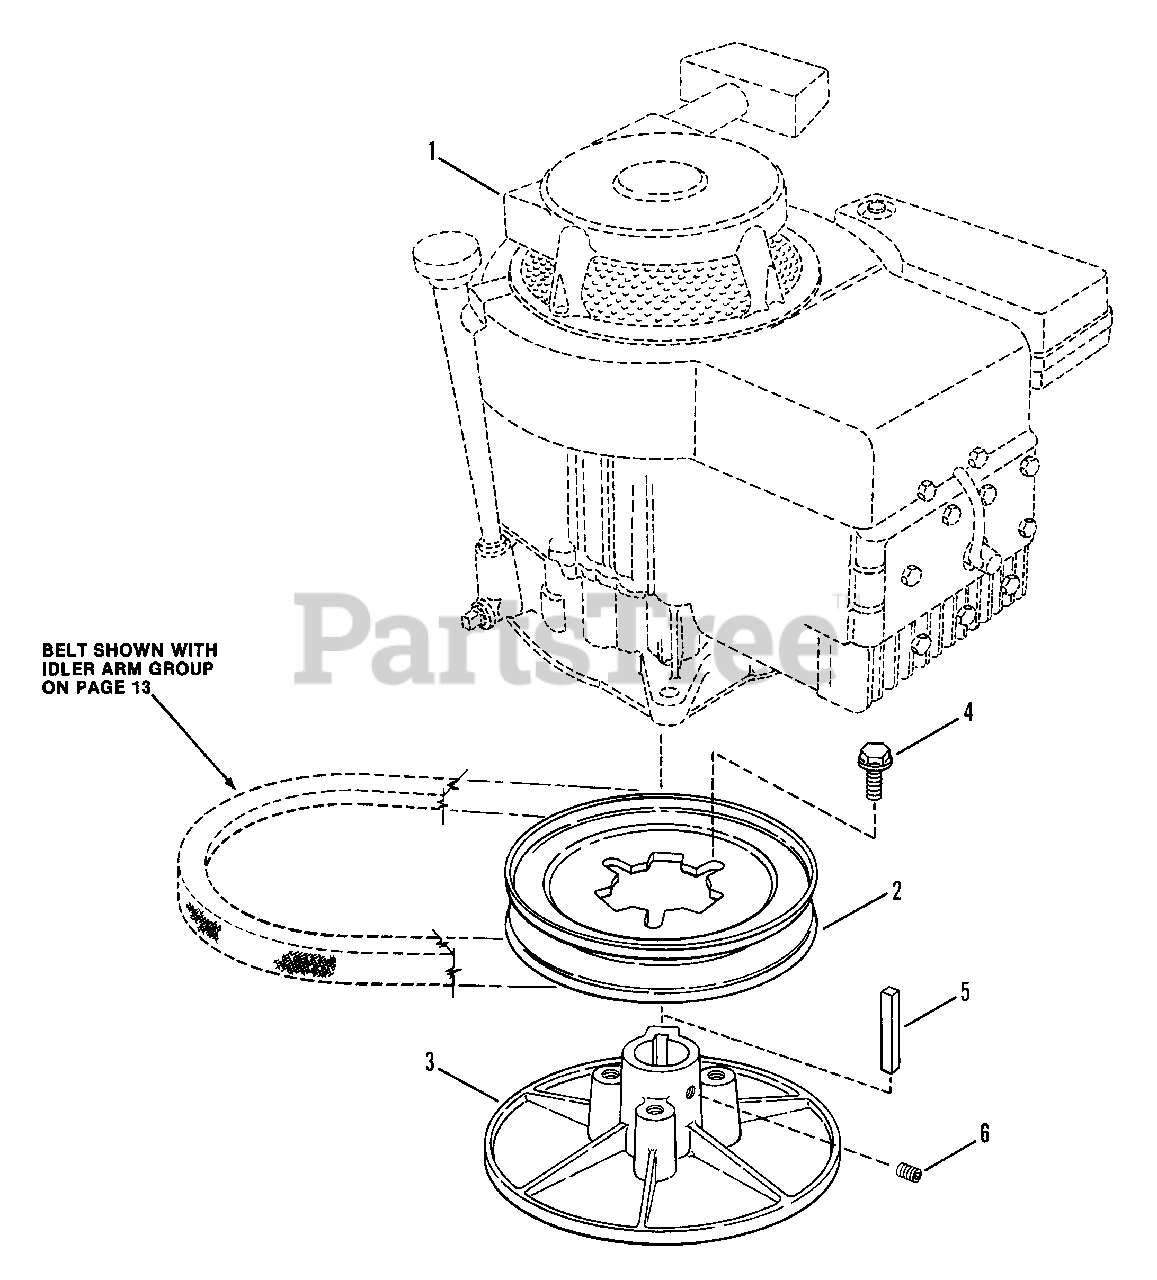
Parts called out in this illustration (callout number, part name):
2	PULLEY, Drive Disc
3	DRIVE DISC
4	SCREW, 1/4-20 x 5/8" Self-Tapping
5	KEY, 1/4 x 1/4 x 2"
6	SETSCREW, 5/16-18 x 5/16" Hex Socket
